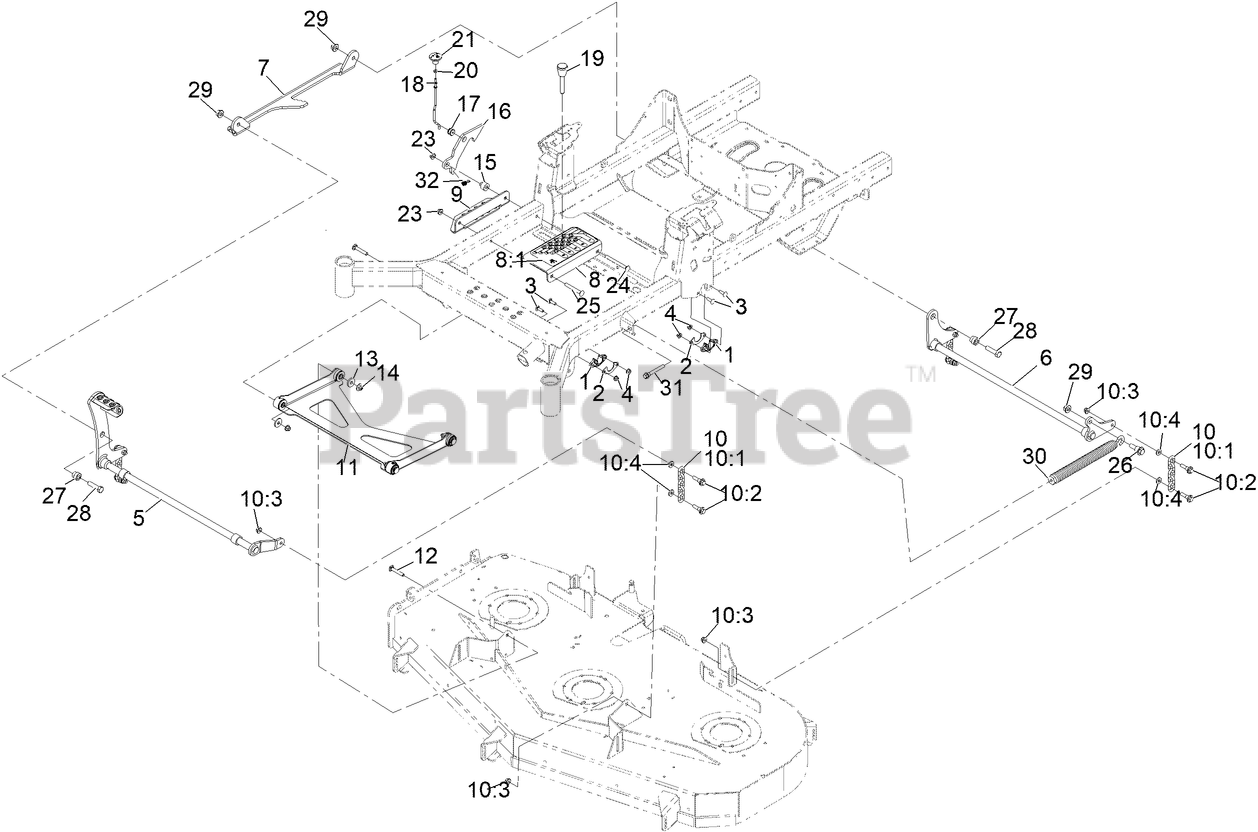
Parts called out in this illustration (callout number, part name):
1	BEARING-FLANGE
2	GUSSET-LIFT, DECK
3	SCREW-CARR
4	NUT-HF, NI
5	Weld-Decklift Front Shaft
6	Weld-Decklift Rear Shaft
7	LINK-DECKLIFT
8	BRACKET ASM
8:1	DECAL-HOC
9	Plate, HOC Lower
10	DECK CHAIN ASM
10:1	CHAIN-LIFT, DECK
10:2	BOLT-SHOULDER
10:3	NUT-HF, NI
11	ASM-DECK STRUT WITH BUSHINGS
12	BOLT-CARR, SHORT NECK
14	Nut-Nyloc 3/8-16 Flg
15	SPACER-STEPPED
16	LATCH, TRANSPORT
17	GROMMET
18	LINKAGE, TRANSPORT
19	PIN-HOC
20	NUT-JAM
23	NUT-HF, NI
24	SCREW-CARR
25	SCREW-CARR
26	SCREW-SHOULDER HHF
27	SPACER, HOC
28	SCREW-HEX
29	NUT-HF, NI
30	SPRING-EXTENSION
31	BOLT-SHOULDER
32	SPRING, EXTENSION
